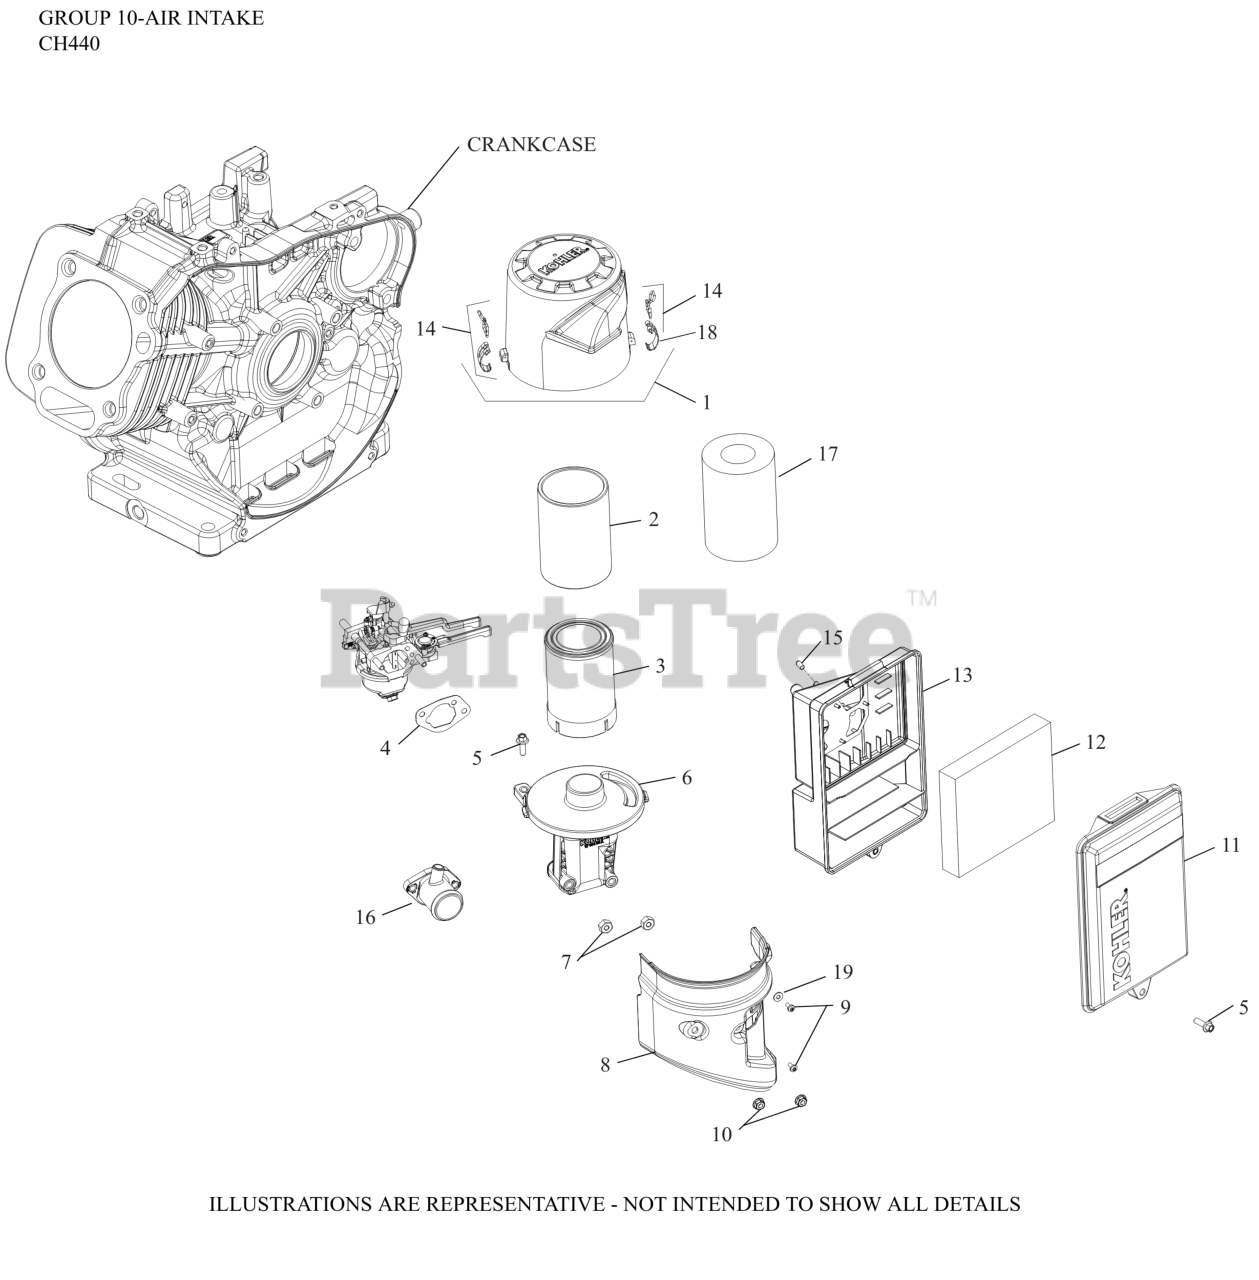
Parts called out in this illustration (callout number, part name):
4	GASKET, AIR CLEANER
5	SCREW, HEX FLANGE SLOTTED (M6)
10	NUT, HEX FLANGE LOCK (M6)
11	COVER, AIR CLEANER
12	ELEMENT, AIR FILTER
13	BASE ASSEMBLY, AIR CLEANER
15	CAP, MASKING (CKY)
